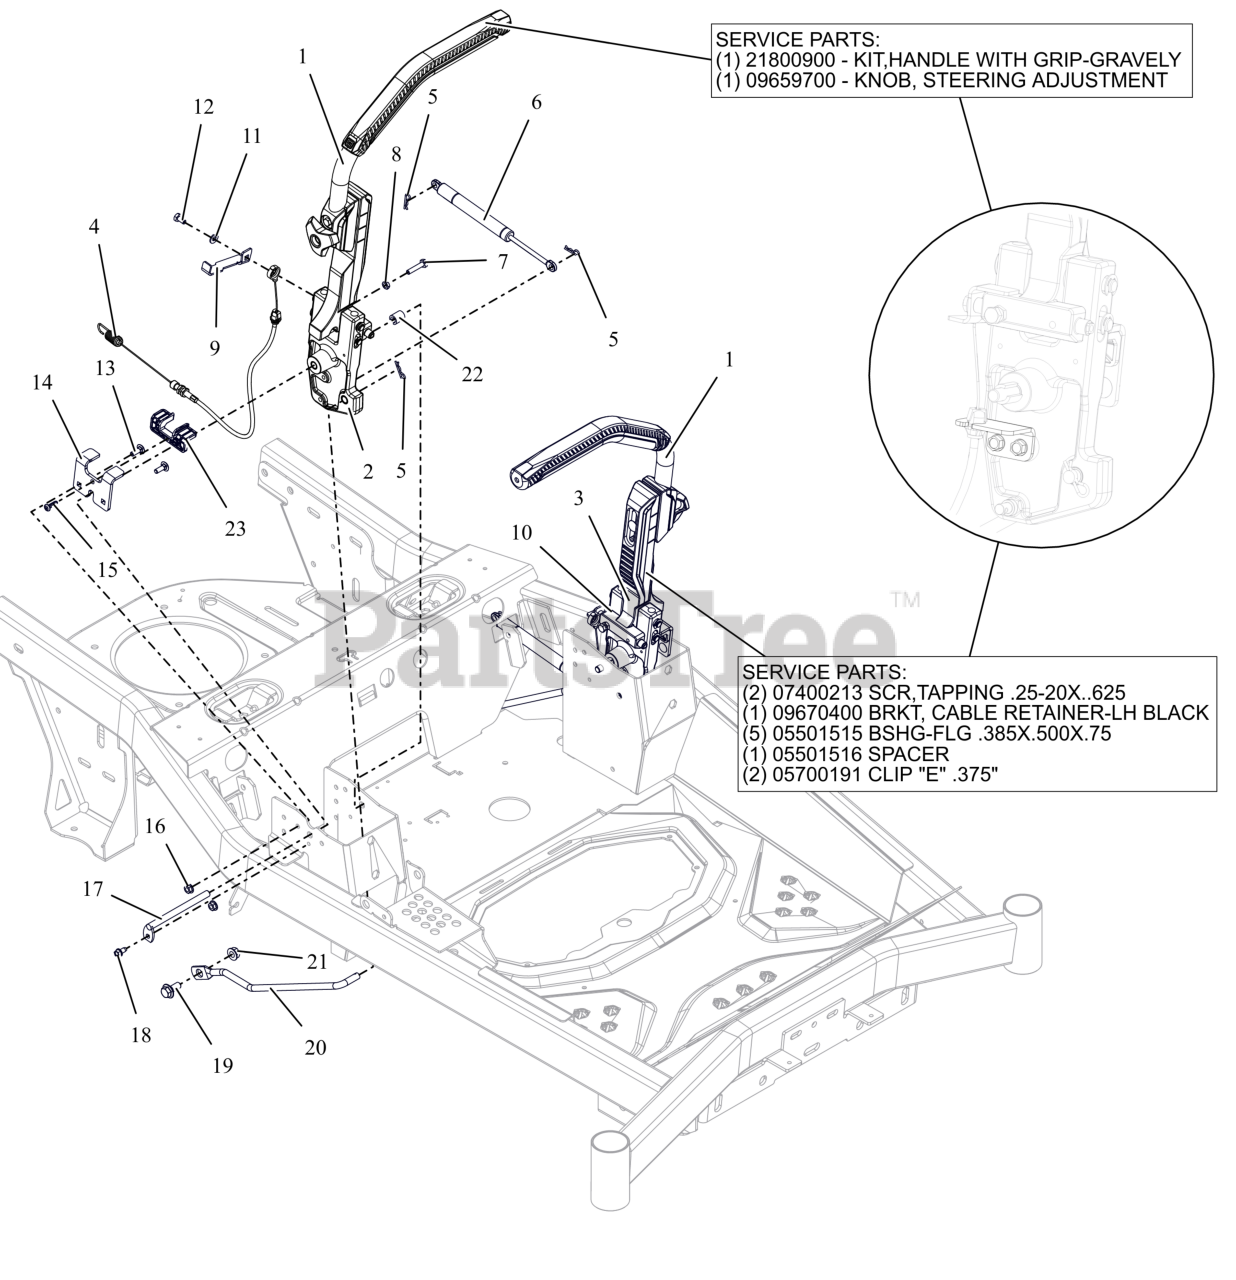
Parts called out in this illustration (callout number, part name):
1	ASM-HANDLE BAR -GRAVELY
1	KIT, TUBE WITH GRIP-GRAVELY
1	KNOB- STEERING ADJUSTMENT
2	ASM- CONTROLS LWR -RH GRAVELY
2	SELF TAPPING SCREW, .25-20X.625
2	BRKT- CABLE RETAINER
2	BSHG-FLG .385X.500X.75
2	SPACER SLEEVED .385X.500X1.045
2	3/8" E RETAINING RING EXTERNAL
3	ASM- CONTROLS LWR -LH GRAVELY
3	SELF TAPPING SCREW, .25-20X.625
3	BRKT5- CABLE RETAINER LH-BLK
3	BSHG-FLG .385X.500X.75
3	SPACER SLEEVED .385X.500X1.045
3	3/8" E RETAINING RING EXTERNAL
4	CABLE- PARK BRAKE
5	PIN, HAIR #213 .08X1.19 ZCC
6	DAMPER- STRAIGHT MOUNT
7	BLT, HEX 0.25-20X1.25F GR5 ZCC
8	NUT-JAM .250-20 G2 ZCC
9	BRKT, PARKING BRK ENG R (BLACK)
10	BRKT, PARKING BRK ENG L (BLACK)
11	WSHR,FLT .281X.625X.065 ZCC
12	BLT, HEX 0.375-16X1 GR5 EP80 ZC120
13	BLT, RHSN .25-20X.750 G5 ZCC
14	PLATE- BRAKE STOP
15	SCR-TAP 12-14X.75PLSTITE @BLZC
16	NUT-LK-CTR-FLG .25-20 ZC120
17	PIN- FIXED STEERING PIVOT
18	SCR-TAP .25-20X.50 HWH ZCC
19	BLT- SHLDR .375-16X.100X.72
20	WIREFORM- STEERING LINKAGE
21	NUT-LK-CTR-FLG .375-16 GF ZCC
22	SPCR- SNAP-ON 1/2 X 1 1/2
23	STEERING, PLASTIC LINER
